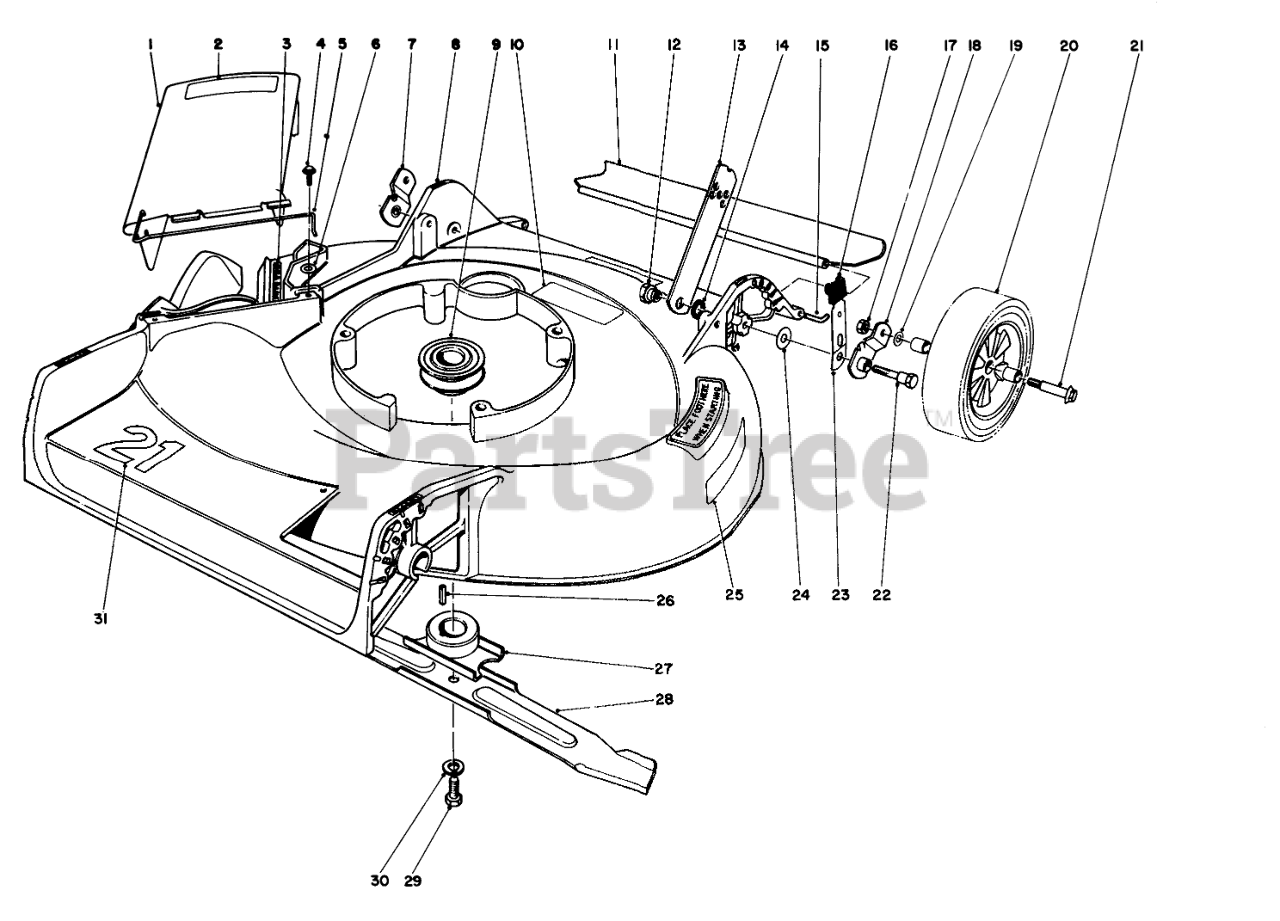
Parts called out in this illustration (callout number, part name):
1	Deflector Cover Assembly (Incl. Ref. #2 & 5)
2	Decal-Caution
3	Decal-Danger
4	SCREW
5	SPRING HINGE
6	WASHER-FLAT
7	Pivot Arm
8	Housing (Incl. Ref. #3, 10 & 25)
9	DRIVER PULLEY
10	Decal-Warning
11	Rear Shield
12	Pivot Nut
13	HANDLE LATCH
14	Spacer-Handle Latch
15	SHIELD ROD
16	KNOB-ARM
18	Pivot Arm
19	WASHER
20	WHEEL TIRE ASM 8 IN
21	BOLT-WHEEL
22	PIVOT SCREW
23	SPRING ARM ASM
24	Washer
25	Decal-Step
26	KEY-SQUARE
27	Blade Retailer
28	Blade
29	SPECIAL SCREW
30	WASHER-LOCK
31	Decal 21"
